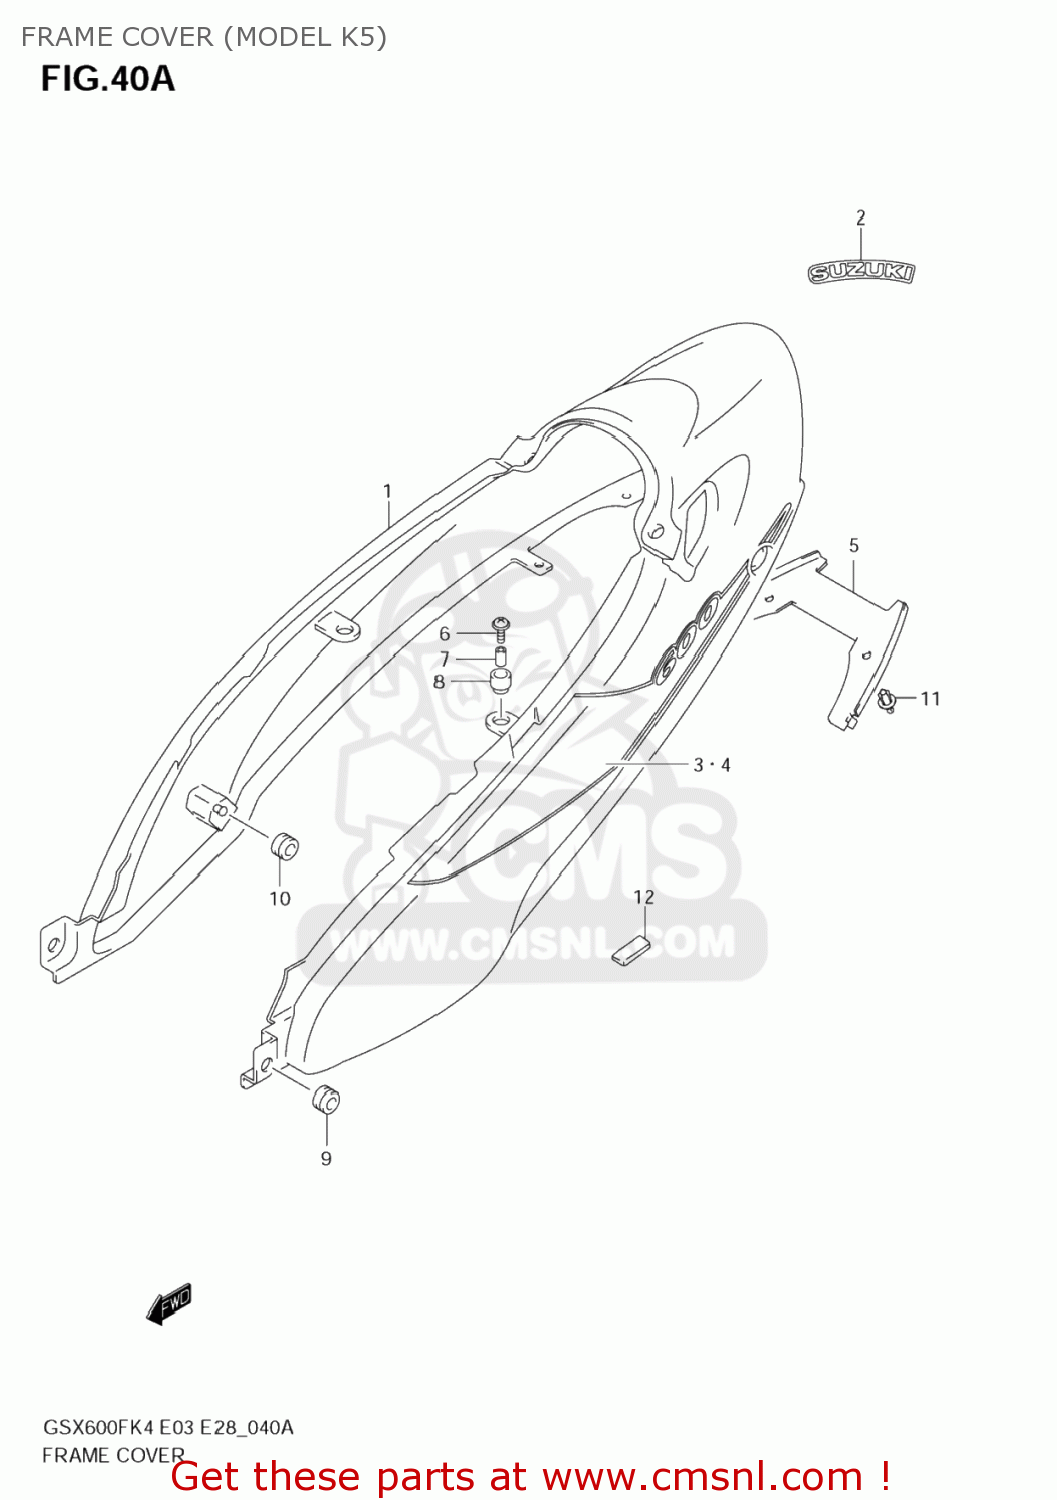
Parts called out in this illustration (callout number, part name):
1	COVER,FRAME(RED)
2	EMBLEM,SUZUKI
3	TAPE,FRAME COVER,R
4	TAPE,FRAME COVER,L
5	COVER,FRAME LWR
6	SCREW(6X20)
7	SPACER(6.5X10X9.4)
8	CUSHION
9	CUSHION
10	CUSHION
11	CLIP(BLACK)
12	CUSHION
